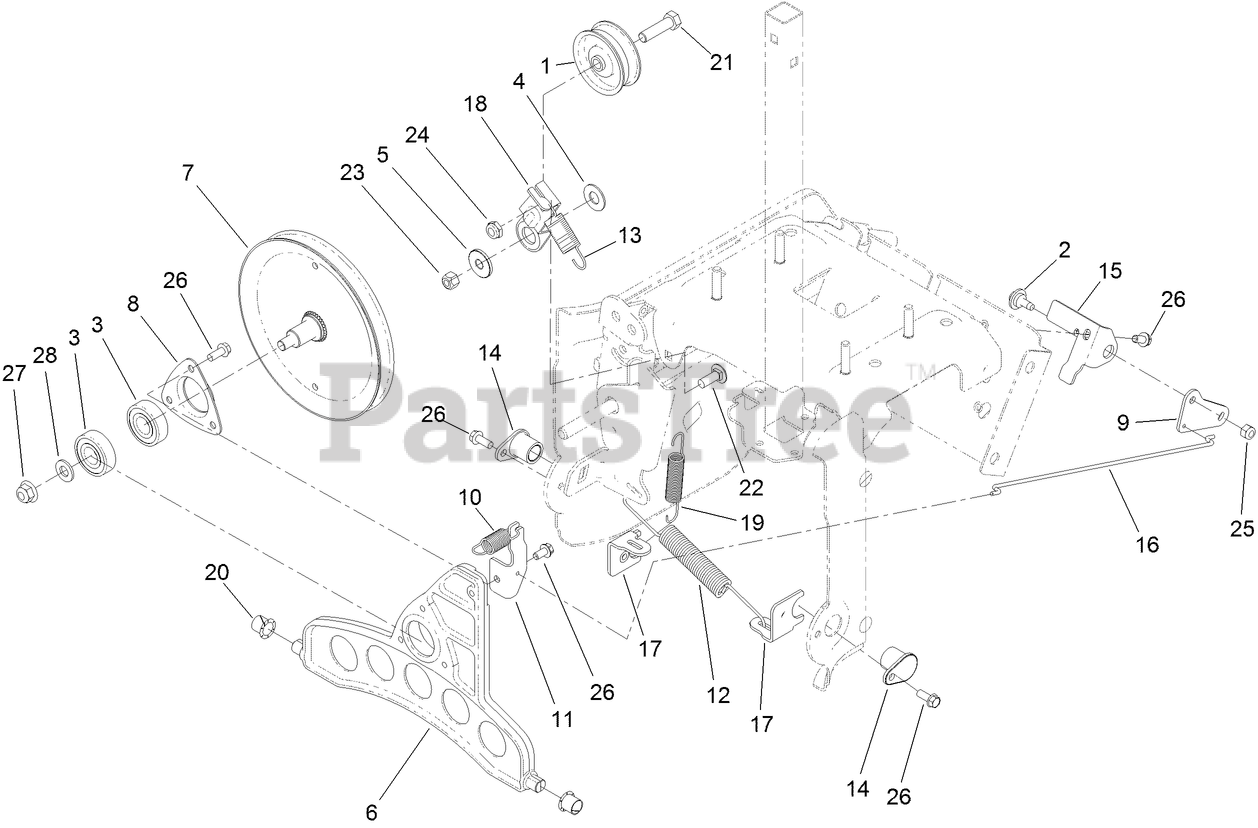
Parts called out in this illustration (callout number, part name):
1	PULLEY-IDLER
2	SCREW-SHOULDER
3	BEARING-BALL
5	BUSHING-IDLER
6	PLATE-WHEEL, FRICTION
7	TRACTION PULLEY ASM
8	RETAINER-BEARING
9	BELLCRANK-DRIVE
10	SPRING-EXTENSION
11	BRACKET-PLATE, TRACTION
12	SPRING-EXTENSION
13	SPRING-EXTENSION
14	BUSHING-PLATE, TRACTION
15	BRACKET-BELLCRANK
16	LINK-DRIVE
17	BRACKET-ANCHOR, SPRING
18	ARM-IDLER, TRACTION
19	SPRING-EXTENSION
20	BUSHING-NYLINER
21	SCREW-HH
22	BOLT-CARR
23	NUT-LOCK, NI
25	NUT-LOCK, NI
26	SCREW-HWH
27	NUT-HF, NI
28	WASHER-FLAT
